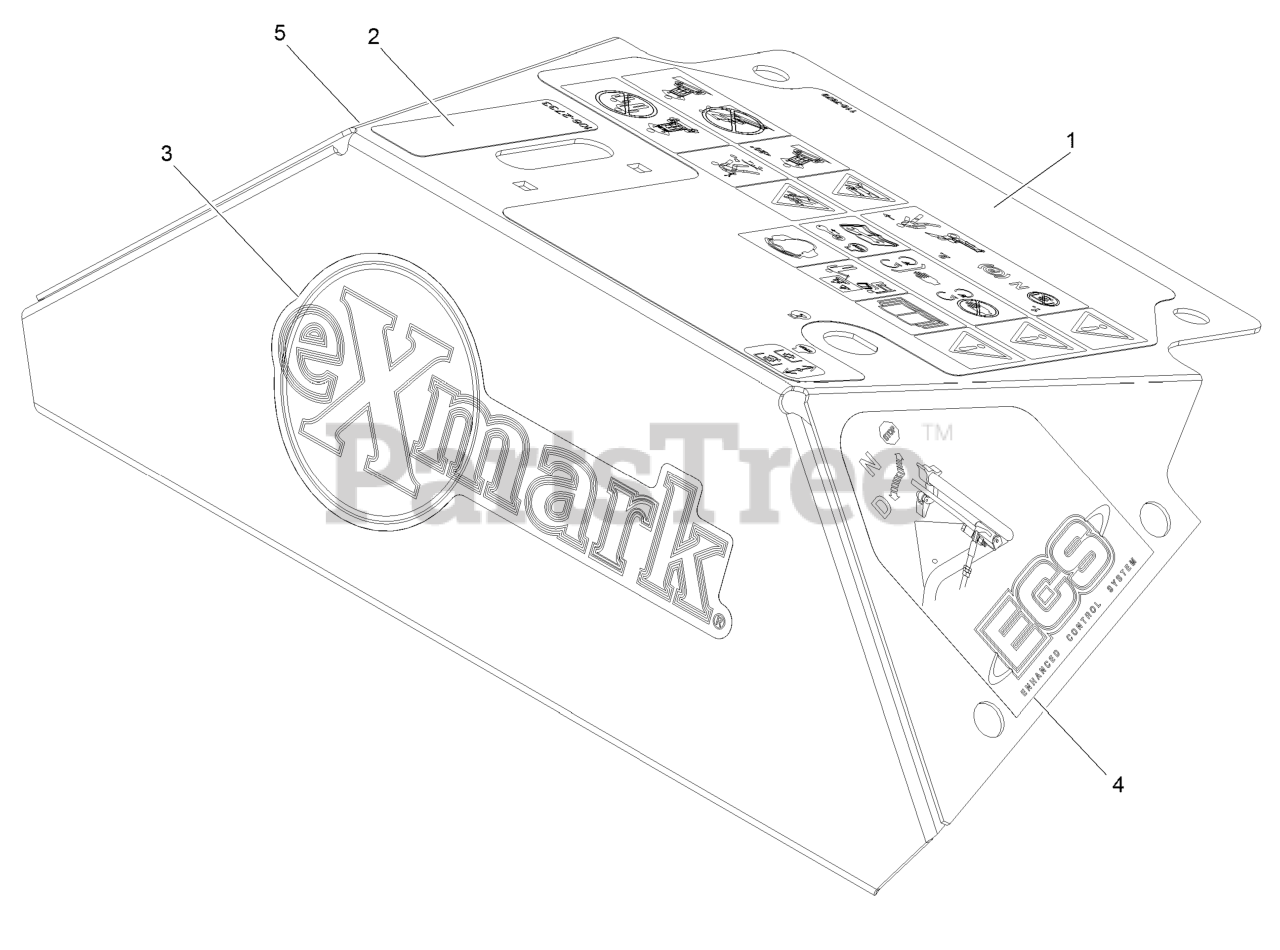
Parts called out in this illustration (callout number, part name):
1	Decal-Console
2	Decal-Throttle
3	Decal, Exmark Logo
4	Decal, LH Ecs Instruction
5	Decal, RH Ecs Instruction
